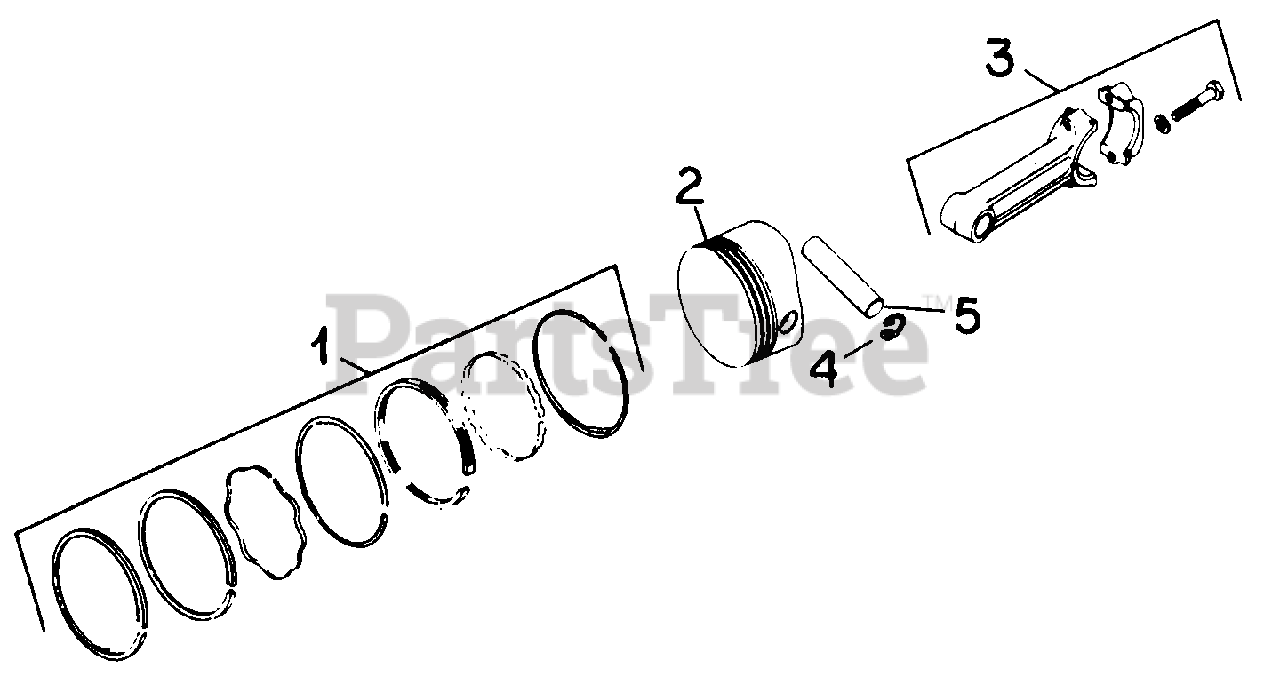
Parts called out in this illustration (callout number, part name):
1	Ring Set, Piston
2	Piston w/Ring Set, Std
3	Rod, Connecting, Std
4	Retainer, Piston Pin
5	Pin, Piston - Not Serviced Separately
